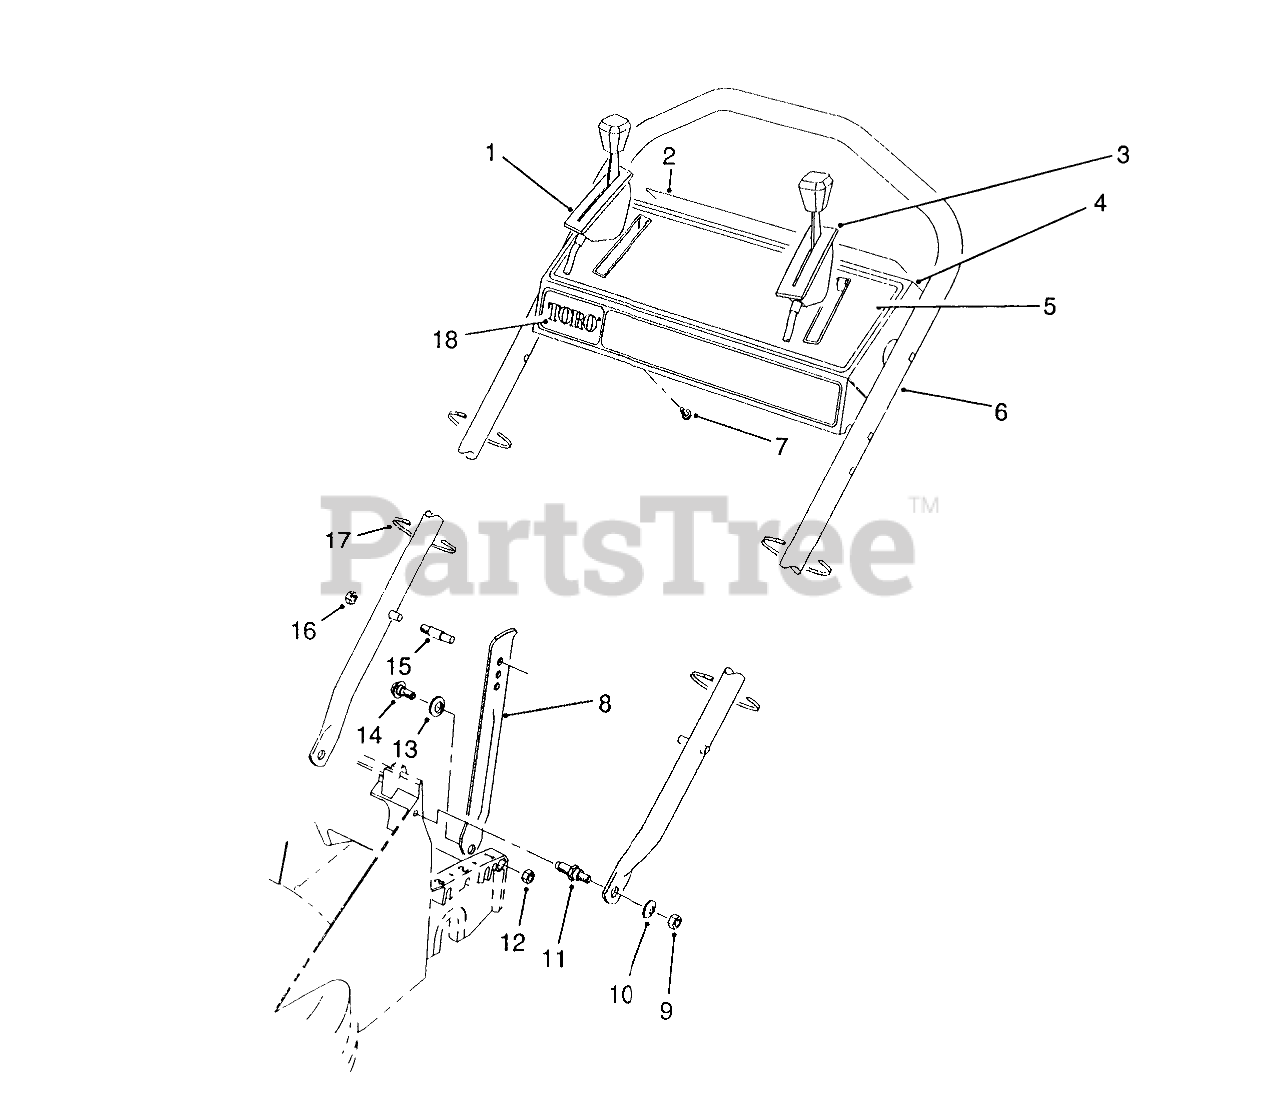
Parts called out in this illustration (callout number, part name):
1	GROUND SPEED CONTROL
2	DECAL - PANEL, REAR
3	ControI-Throttle Bend Type #2 Sheath Lg. 44-3/4" Wire Lg. 2-1/2"
4	Control Panel Assembly (Incl. Ref. #2 & 5)
5	DECAL - INSTRUCTION
6	HANDLE
7	SCREW-HWHTF
8	HANDLE LATCH
9	NUT-LOCK, NI
10	WASHER-PLAIN
11	SHOULDER SCREW STUD
12	NUT-LOCK, NI
13	NYLON WASHER
14	SCREW-SHOULDER
15	HANDLE PIN
16	NUT-LOCK, NI
17	TIE-CABLE
18	DECAL - TORO PANEL
